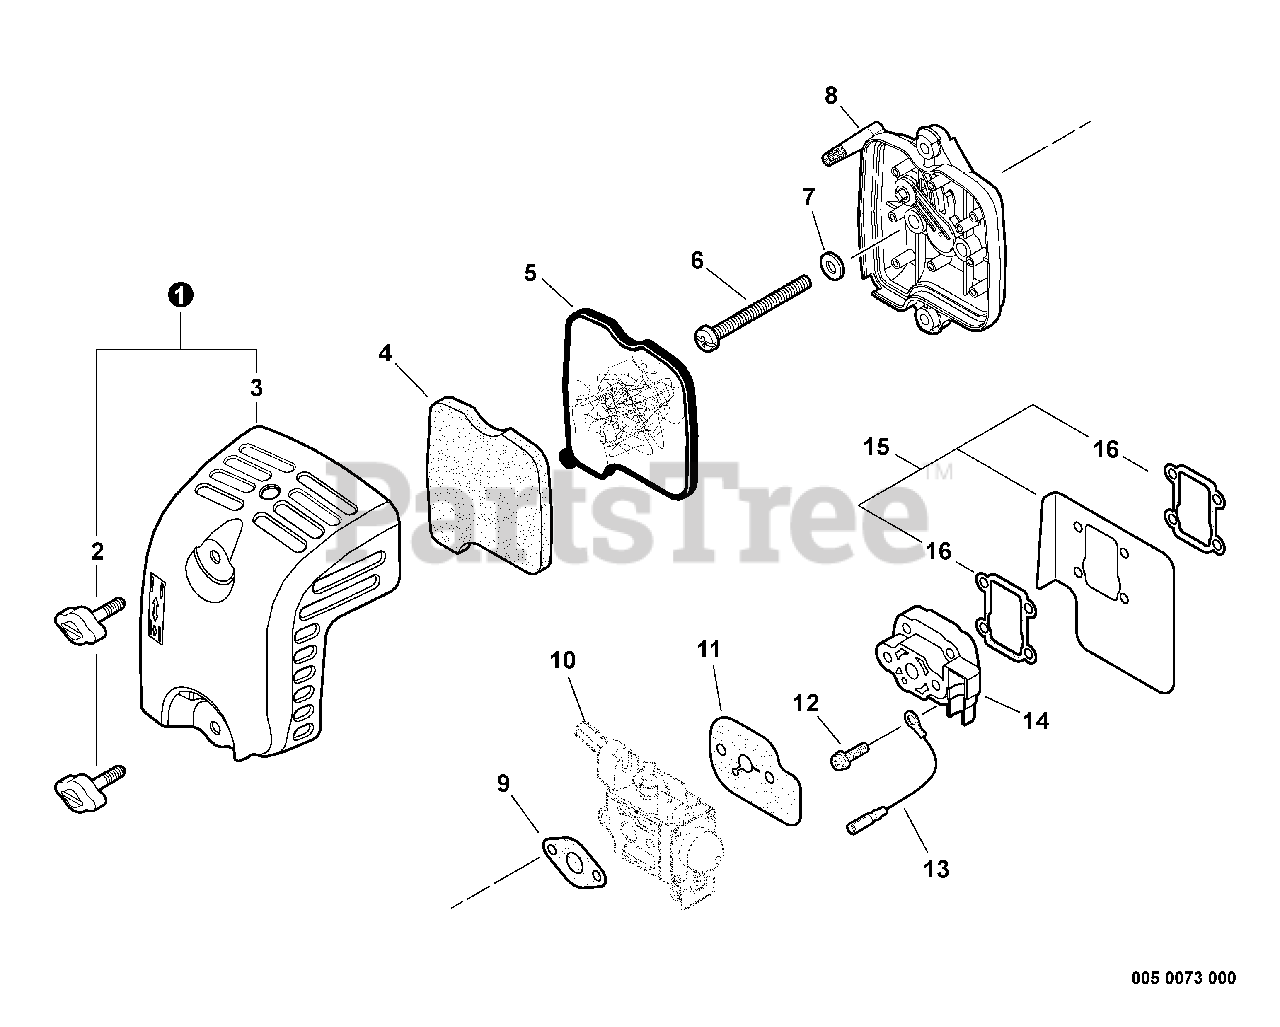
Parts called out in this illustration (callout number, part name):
1	COVER ASSY, AIR FILTER
2	THUMBSCREW M5
3	COVER, AIR FILTER
4	PRE-FILTER, FOAM
5	FILTER, AIR
6	SCREW M5×60
7	WASHER 5.5×12×0.8
8	CASE ASSY, AIR FILTER
9	GASKET, INTAKE
10	CARBURETOR
11	GASKET, INTAKE
12	SCREW M5×22
13	LEAD - GROUND L= 110 MM
14	INSULATOR WITH REED VALVE
15	SHIELD ASSY, INTAKE HEAT
16	GASKET, EXHAUST
